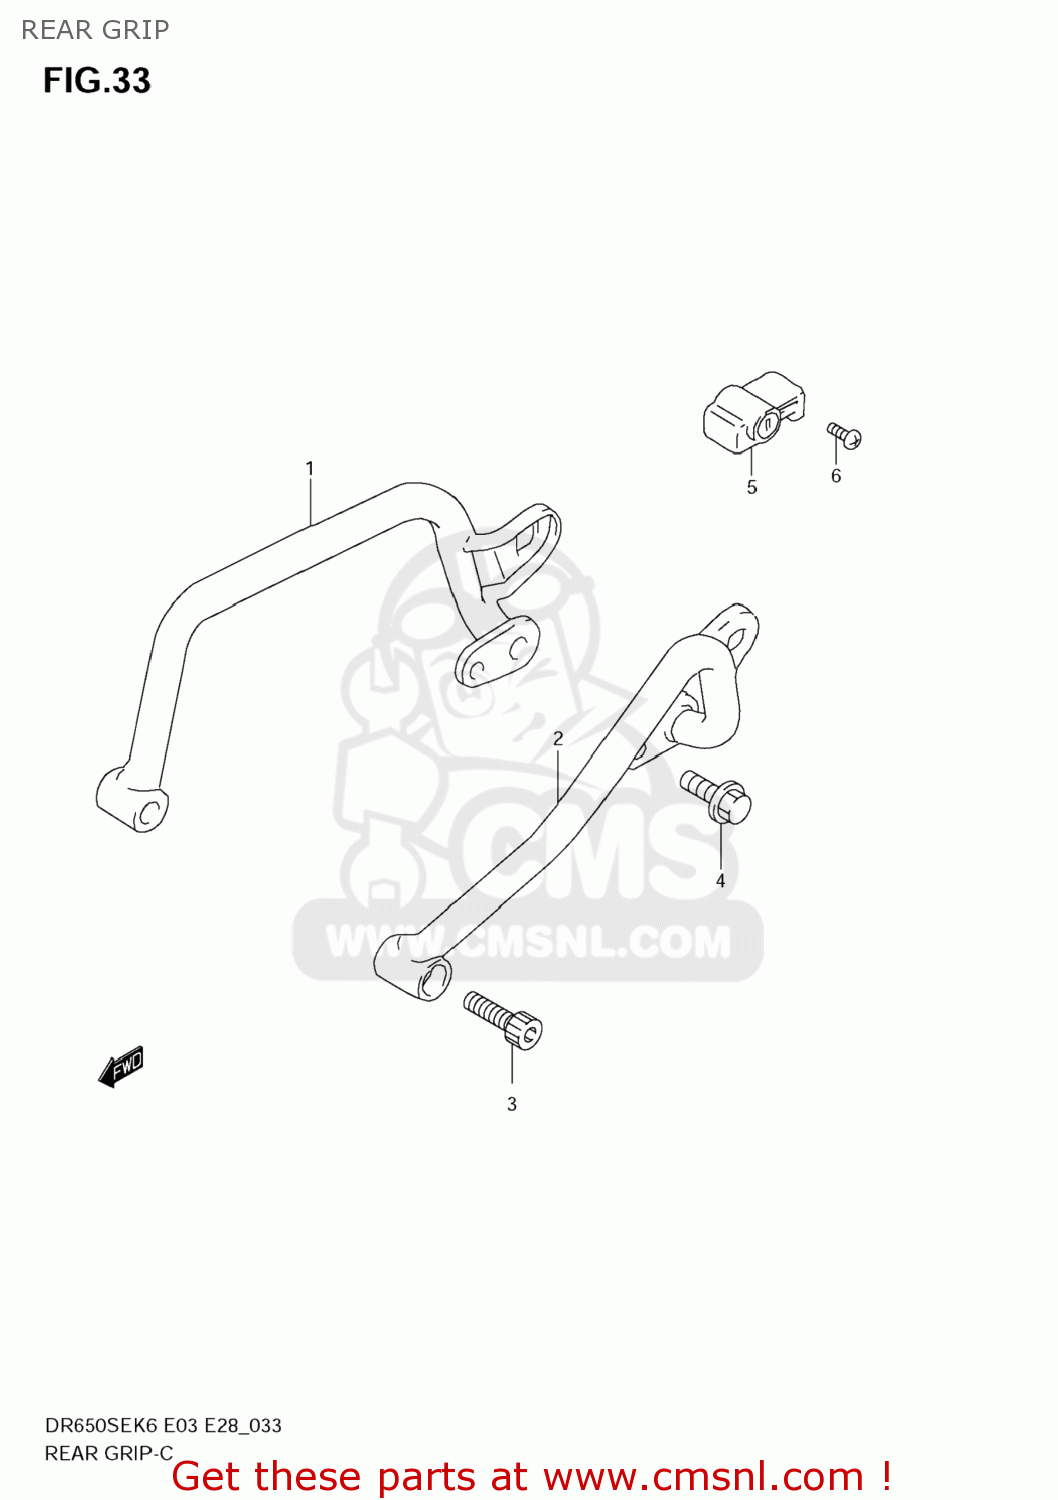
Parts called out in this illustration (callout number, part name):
1	GRIP,RR,R
2	GRIP,RR,L
3	BOLT
4	BOLT
5	LOCK SET,HELMET
6	SCREW(6X14)
